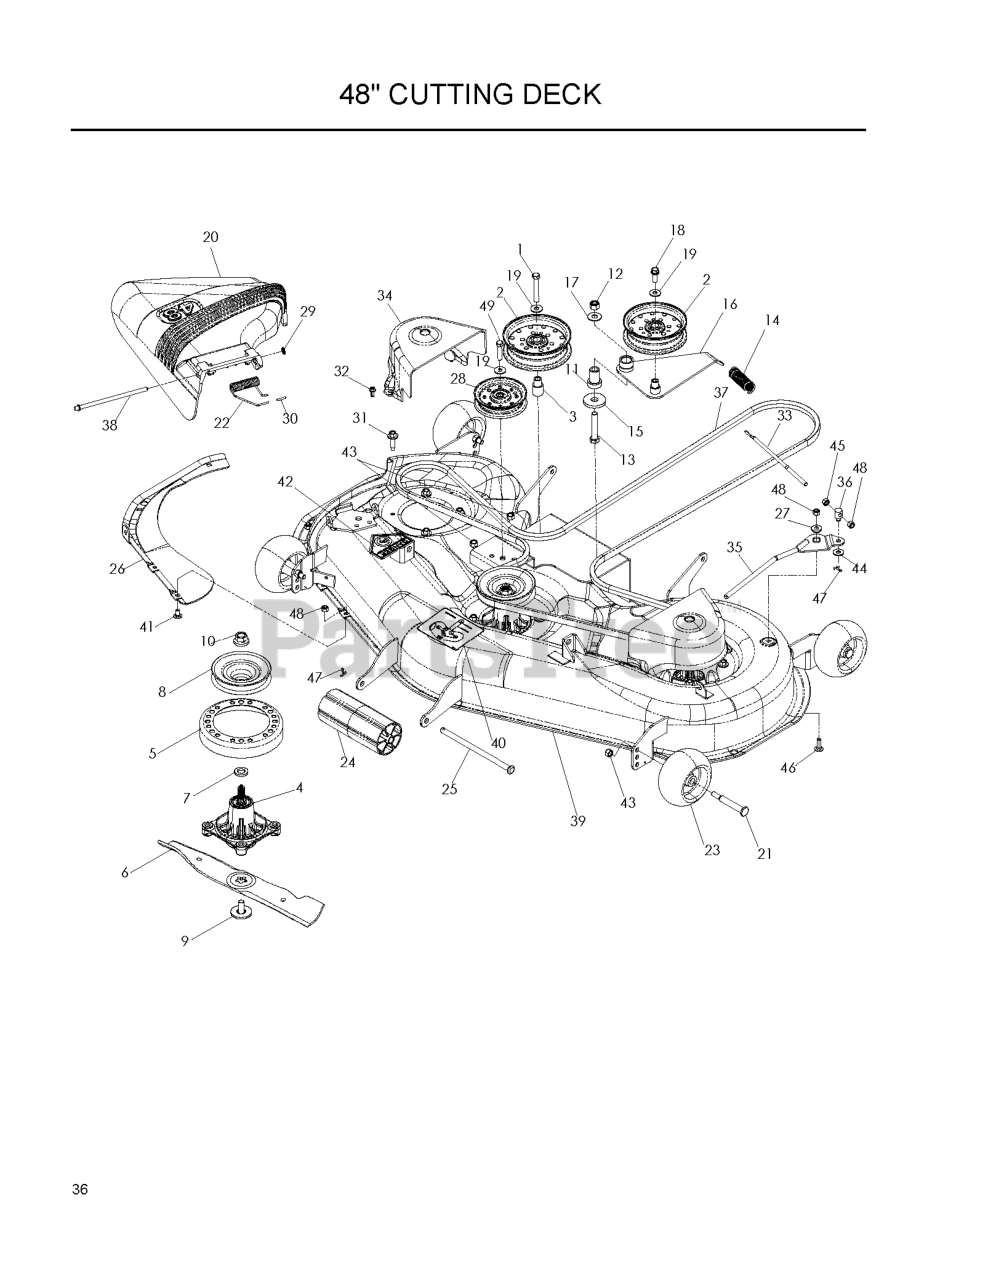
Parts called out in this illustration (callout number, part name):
1	SCREW 3/8C X 2 3/4 HEX CAP
2	IDLER PULLEY
3	IDLER BUSHING
4	CUTTER HOUSING
5	STRIPPER-ROUND-UNIVERSAL
6	BLADE-HIGH LIFT/48"
7	WASHER-SPACER
8	DRIVEN PULLEY-48"
9	BLADE BOLT ASSY-7/16" TB REPL
10	LOCKNUT - 9/16
11	IDLER SPINDLE
12	NUT 1/2-13 HEX NYLOC ZD
13	SCREW, 1/2C X 3 HEX CAP
15	WASHER, SUPPORT
16	DECK IDLER ARM
17	WASHER 1/2 FLAT
18	4CS 3/8C X 1 SERRATED HEAD
19	WASHER 5/16 FLAT
20	DISCHARGE CHUTE
21	SHOULDER BOLT 1/2X2-5/8 ZD SPE
22	TORSION SPRING
23	GAUGE WHEEL
24	NOSE ROLLER-48"
25	NOSE ROLLER ROD
26	VORTEX MOWER BAFFLE
27	PIVOT BUSHING
28	FLAT IDLER PULLEY
29	PUSH NUT
30	CAP-SLEEVE
31	WASHER HEAD SCREW
32	SCREW- 1/4-20 X 5/8
33	TENSION RELIEF LINKAGE
34	BELT SHIELD
35	TENSION RELIEF LEVER BLK
37	BELT, DECK
38	ROD, HINGE
39	DECK SVC W/DECALS HUSQ ORANGE
40	DECAL, BELT ROUTING
41	CARRIAGE BOLT 5/16C X 5/8"
42	DECAL, CPSC
43	NUT 3/8-16 NYLOC
44	WASHER 3/8 SAE FLAT
45	NUT 5/16C HEX
46	RHSNB 5/16C X 1
47	RP_COTTER PIN 1/8 X 3/4
48	NUT 5/16 NYLOC
49	HCS 3/8-16 X 1 3/4 GR5
